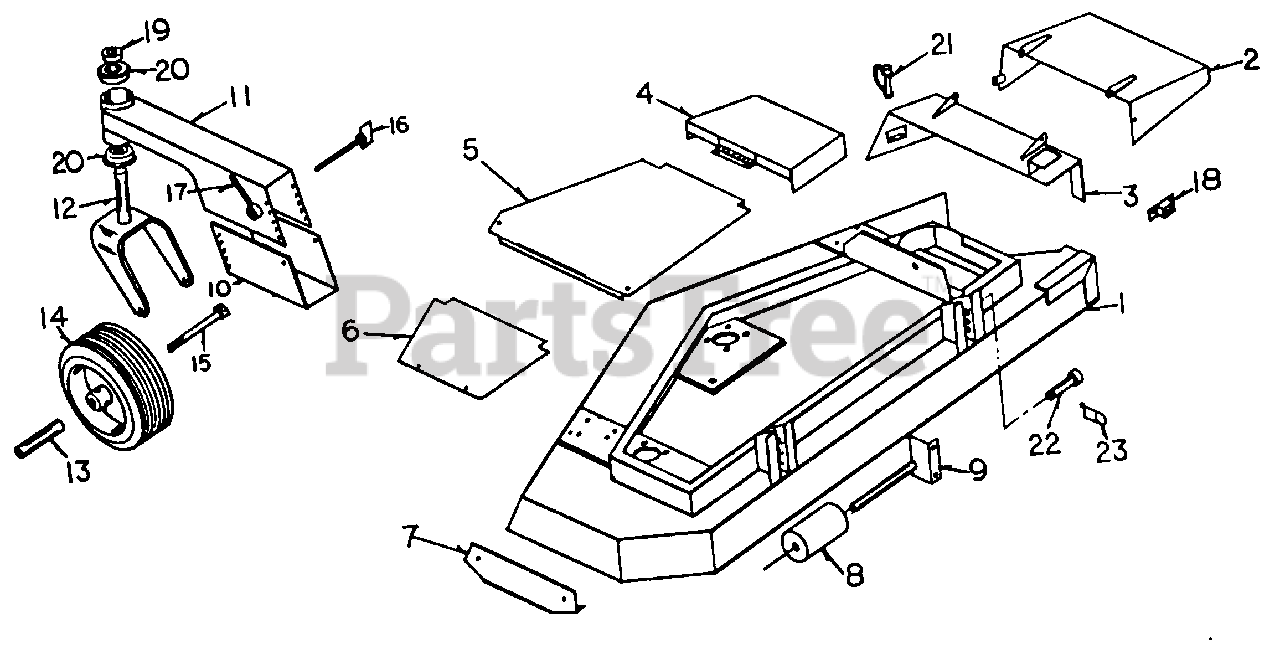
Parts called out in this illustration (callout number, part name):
3	Foot Guard Mount
8	Anti-scalp Roller
9	Shaft & Bracket
10	Gauge Wheel Mount Bracket
11	6auge Wheel Mount
13	Axle
14	Gauge Wheel Assembly
15	Hex Bolt, 1/4-20 x 4 1/2", GRS
18	10 Amp Circuit Breaker
19	Set Collar, 1"
23	Hair Pin Cotter
